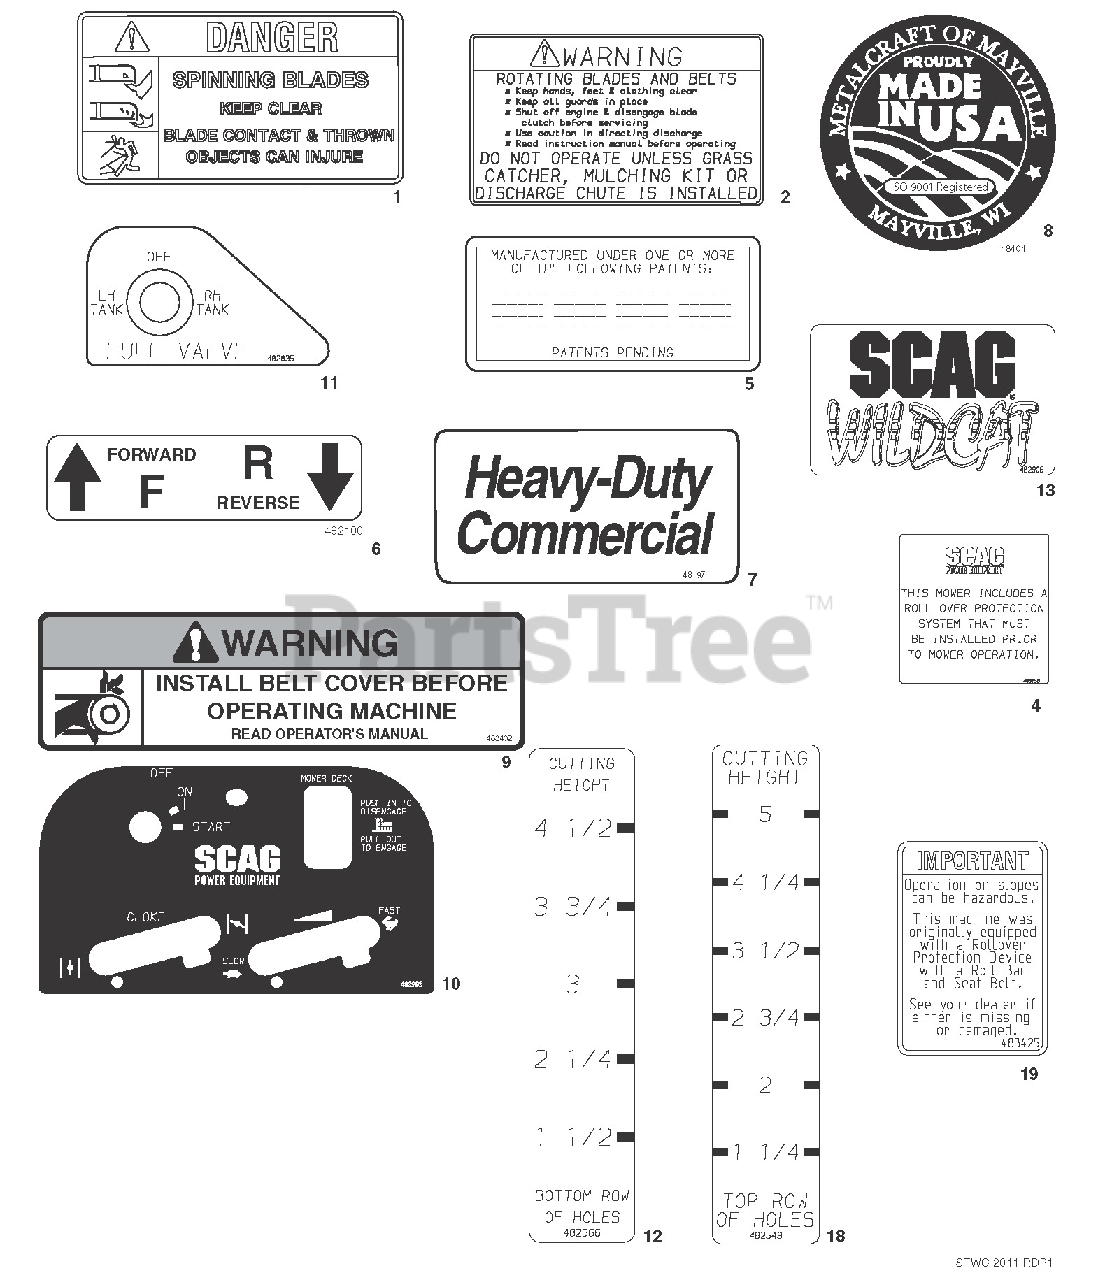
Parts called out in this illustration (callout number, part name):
1	Decal, Danger-Spinning Blades
2	Decal, Warning-Rotating Blades
4	Decal, ROPS
5	Decal, Patents
6	Decal, Traction Control
7	Decal, Heavy Duty Commercial
8	Decal, Metalcraft - Made in USA
9	Decal, Belt Cover
10	Decal, Instrument Panel
11	Decal, Fuel Valve Position
12	Decal, Cutting Height Bottom Row of Holes
13	Decal, Wildcat
18	Decal, Cutting Height Top Row of Holes
19	Decal, ROPS
